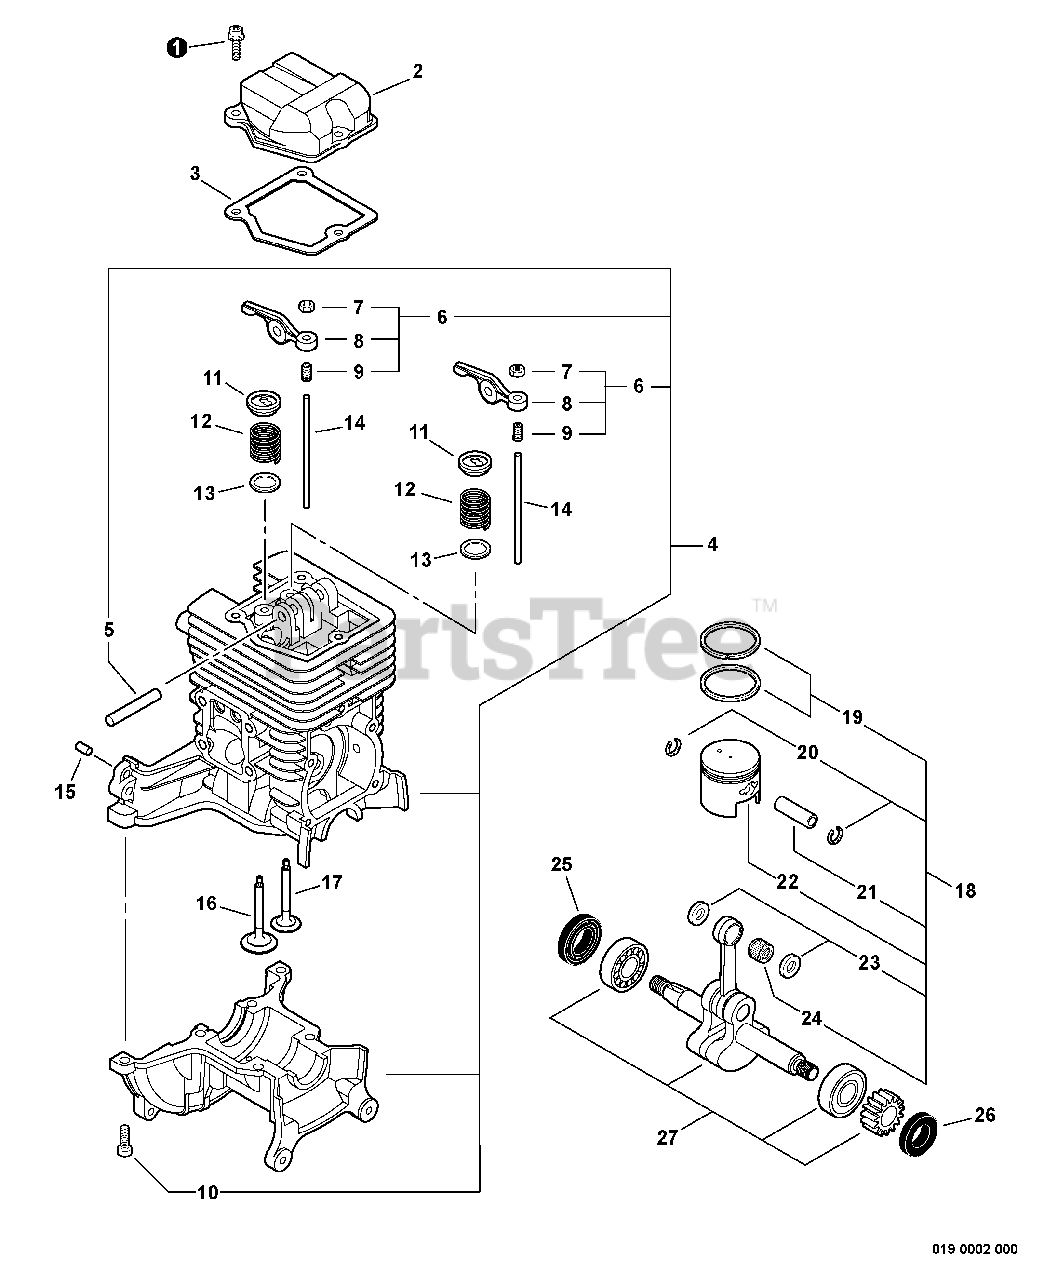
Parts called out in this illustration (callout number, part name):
1	SCREW - 4X14
2	COVER, ROCKER ARM
4	CYLINDER KIT
5	SHAFT, ROCKER ARM
6	ROCKER ARM ASSY
7	LOCKNUT - 5
8	ARM, ROCKER
9	SCREW, ADJUST
10	SCREW - 5X16
11	RETAINER, VALVE
12	SPRING, VALVE
13	WASHER, VALVE - 9
14	PUSHROD
15	PIN - LOCATING
16	VALVE, INTAKE
17	VALVE, EXHAUST
18	PISTON KIT
19	RING, PISTON
20	RING, RETAINING
21	PIN, PISTON
23	SPACER - 9
24	BEARING, NEEDLE
25	SEAL, OIL
26	SEAL, OIL - 12
27	CRANKSHAFT ASSY
